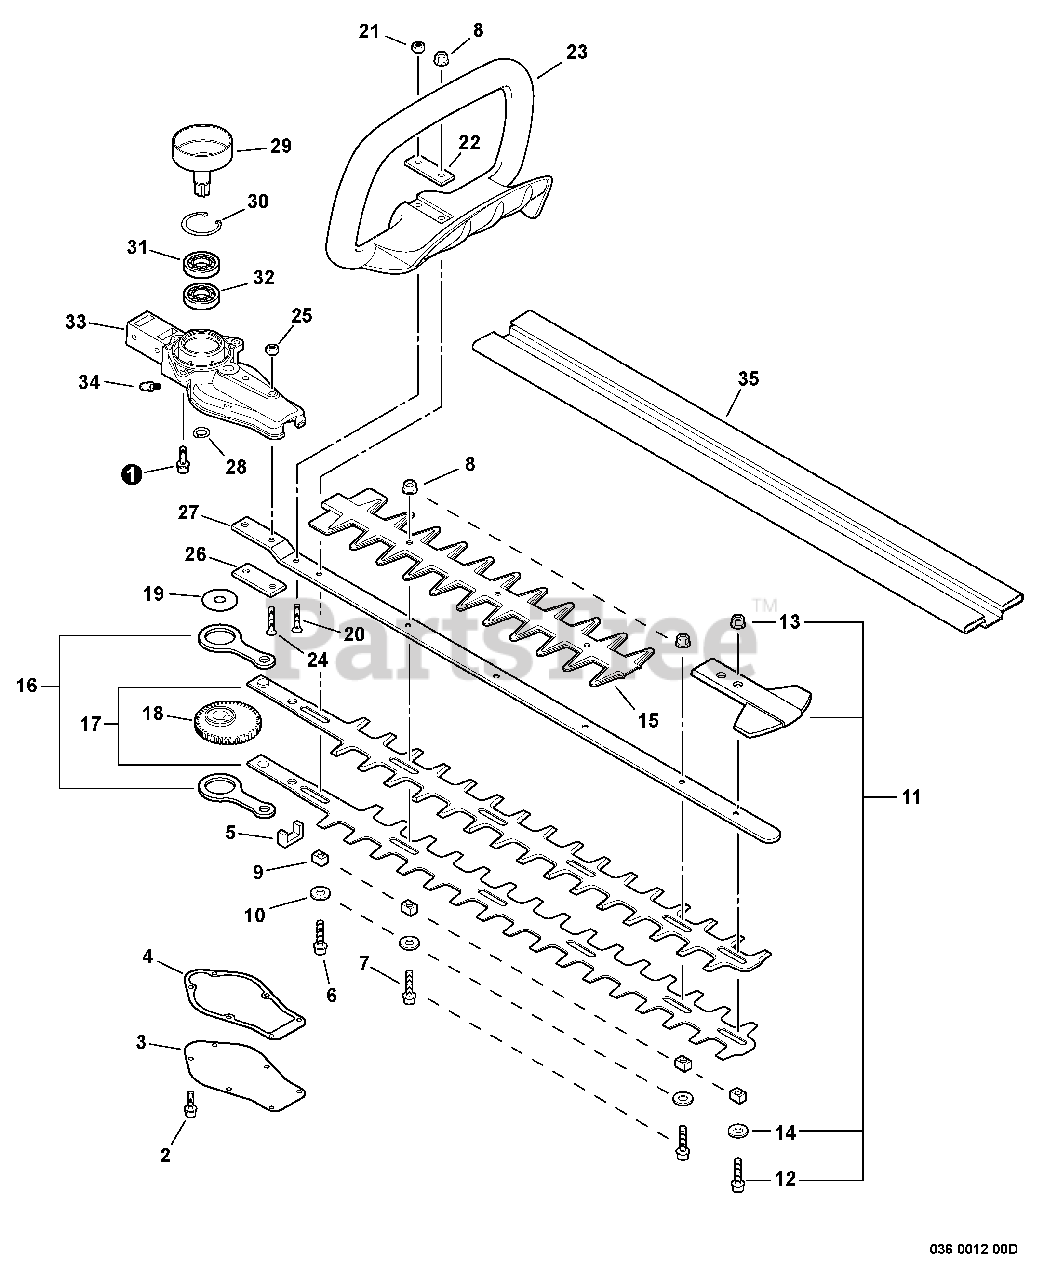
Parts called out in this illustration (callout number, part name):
1	SCREW - 5X20
2	SCREW - 4X10
3	LID, GEAR CASE
4	GASKET, GEAR CASE
5	SEAL, FELT
6	SCREW - 5X40
7	SCREW - 5X20
8	LOCKNUT - 5
9	GUIDE, BLADE
10	WASHER - 6
11	TIP GUARD KIT
12	SCREW - 5X20
13	LOCKNUT - 5
14	WASHER - 6
15	SHIELD, BLADE
16	ROD, CONNECTING
17	BLADE - 20" (50cm)
18	GEAR - DRIVE
20	SCREW - 5X30
21	LOCKNUT - 5
23	HANDLE - FRONT
24	SCREW - 6X25
25	LOCKNUT - 6
27	SUPPORT, BLADE
28	RING, RETAINING - 14
29	DRUM, CLUTCH
30	RING, RETAINING - 35
31	BEARING, BALL - 6202
31	COVER, BLADE - 20" (50cm)
32	BEARING, BALL - 6202
33	CASE, GEAR
34	FITTING, GREASE
